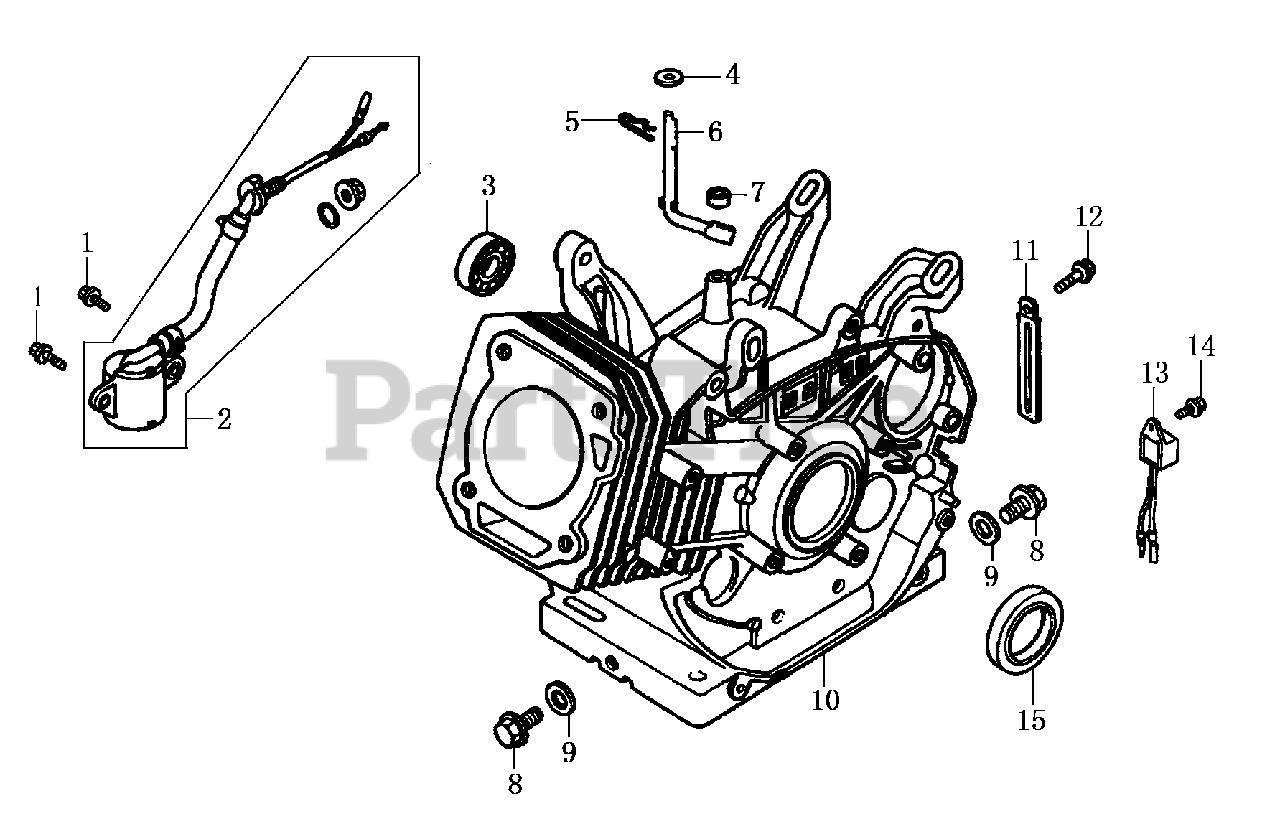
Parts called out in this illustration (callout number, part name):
1	BOLT, FLANGE
2	SWITCH ASSY., OIL LEVEL
3	BEARING, RADIAL BALL, 6202
4	WASHER,8X16X1.2
5	PIN, LOCK, 10MM
6	SHAFT, GOVERNOR ARM
7	OIL SEAL, 8X14X4
8	BOLT, DRAIN PLUG
9	WASHER, DRAIN PLUG, 12MM
10	CRANKCASE (ELECTRIC START)
11	CABLE CLEAT
12	BOLT, FLANGE, 6X12
13	ALERT UNIT,OIL
14	BOLT, FLANGE, 6X12
15	SEAL, OIL
